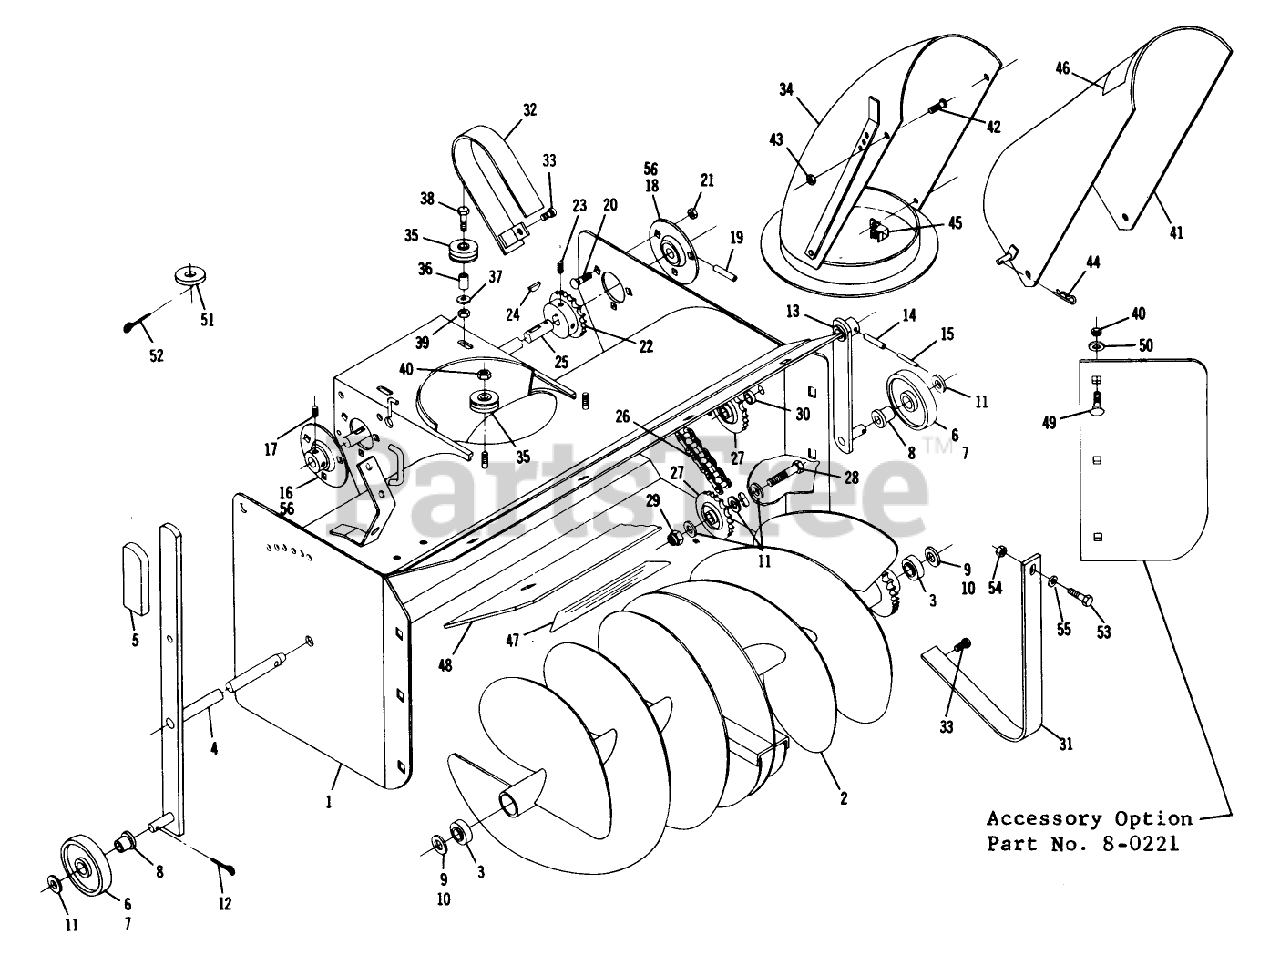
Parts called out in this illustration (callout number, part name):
1	Wrapper Ass-y
2	Auger
3	BEARING-BALL
4	Auger Shaft
5	GRIP
6	WHEEL BUSHING ASSY R
7	Wheel
8	Bushing
9	Washer
10	WASHER
11	Washer
12	Cotter Pin
13	Wheel Support
14	ROLL PIN 1/4 X 1-1/4
15	PIN-SPIROL
16	Ball Bearing
17	Set Screw
18	Ball Bearing
19	PIN-ROLL, SPIROL
20	Bolt Hex 5/16-18 x 3/4
21	Nut-Nylok
22	SPROCKET
23	Set Screw Nylok
24	Key
25	Shaft-Drive
26	CHAIN
27	Idler Sprocket
28	Bolt-1/2-13-1 3/4
29	Locknut-1/2-13
30	SPACER
31	Guard-Inner
32	Guard-Outer
33	SCREW
34	S/A SHROUD R
35	Roller
36	SPACER
37	Washer
38	Bolt 1/4 20 x 1 1/4
39	Nut-Nylok
40	3/8-16 E.S.
41	Deflector
42	Bolt Pan Head 1/4-20 x 1/2
43	Nut, 1/4-20
44	Hairpin
45	CLAMP
46	Decal-Caution
47	Decal
48	Plate-Top Extension
49	Bolt 3/8-16 x 1
50	Washer
51	Washer, 5/8
52	Cotter Pin 3/16 x 1
53	Bolt-1/4-20 x 5/8
54	Nut 1/4-20 Keps
55	Washer
56	FLANGE
